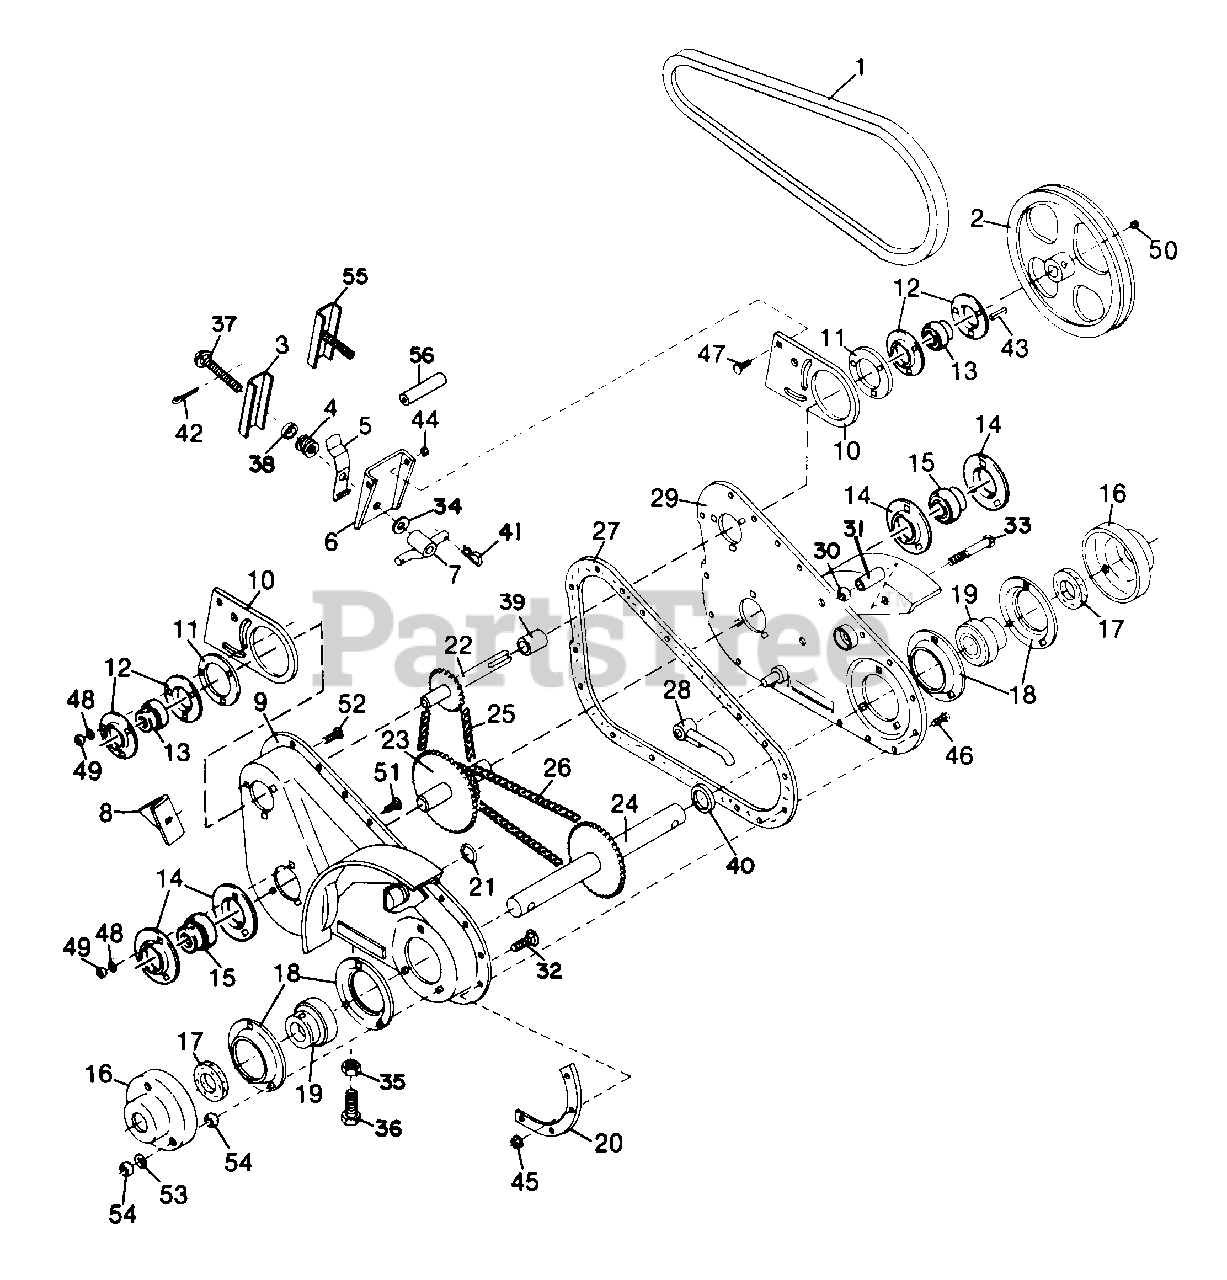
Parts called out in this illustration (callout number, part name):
1	BELT, DRIVE
2	PULLEY, DRIVE
3	HANDLE, ADJUSTMENT -2B TILLER-
4	SPRING, COMPRESSION
5	CLIP, ADJUSTMENT STOP -2B TILLER-
6	CHANNEL, BELT TIGHTENER
7	ROD, ADJUSTMENT
8	CLIP, MOUNTING BRACKET
9	HOUSING, CHAIN DRIVE
10	PLATE, PIVOT
12	FLANGE, BEARING
13	BEARING W/O LOCKING COLLAR
14	FLANGE, BEARING
15	BEARING W/O LOCKING COLLAR
16	EXCLUDER, DUST
17	GASKET, FELT SEAL
18	FLANGE, BEARING
19	BEARING
20	SHOE, FORMED
22	SHAFT, INPUT
23	SPROCKET, IDLER -10 & 28 T-(TEETH)
24	SHAFT, MAIN DRIVE -18 T-(TEETH)
26	CHAIN, TINE DRIVE
27	GASKET, CHAIN DRIVE HOUSING
28	ADJUSTMENT, CHAIN
29	PLATE, HOUSING BACK
30	NUT, 3/8 CAD P/T LOCK TYPE 8
31	SPACER, 3/8 x 3/4 x 1-3/4
32	BOLT, 3/8 x 1-1/2 CRG TYPE 5
33	BOLT, 3/8 x 2-1/2 PHC TYPE 8
34	WASHER, .531 x 1.062 x .074
35	NUT, 1/2 PLN TYPE 5
36	BOLT, 1/2 x 2 PLN TYPE 5
37	BOLT, ADJUSTMENT -2B TILLER-
38	SPACER, 3/4 x 1 x 1/4 -2B TILLER-
39	SPACER, 3/4 x 1-1/8 x 1-3/8 -2B TILLER-
41	PIN, QUICK ATTACHABLE COT.
42	PIN, 5/32 x 1 COT
43	KEY, 3/16 x 1-5/8 SQ PARALLEL
44	NUT, 1/4 CAD P/T LOCK TYPE 5
45	NUT, 1/4-28 x 3/4, FLANGE LOCK
46	BOLT, 1/4-NF x 3/4 TYPE 5
47	BOLT, 1/4 x 1 CRG TYPE 1
48	WASHER, 5/16 LOCK
49	NUT, 5/16 TYPE 5
50	SCREW, 5/16 x 3/8 PLN C/PT HDL/HS SET
51	BOLT, 5/16 x 3/4 CRG TYPE 5
52	BOLT, 5/16 x 1 CRG TYPE 1
53	WASHER, 3/8 LOCK
54	NUT, 3/8 TYPE 5
55	TEE, BELT ADJUSTMENT -2 TILLER-
56	SPACER, 1/2 x 2-3/4 PIPE -2 TILLER-
